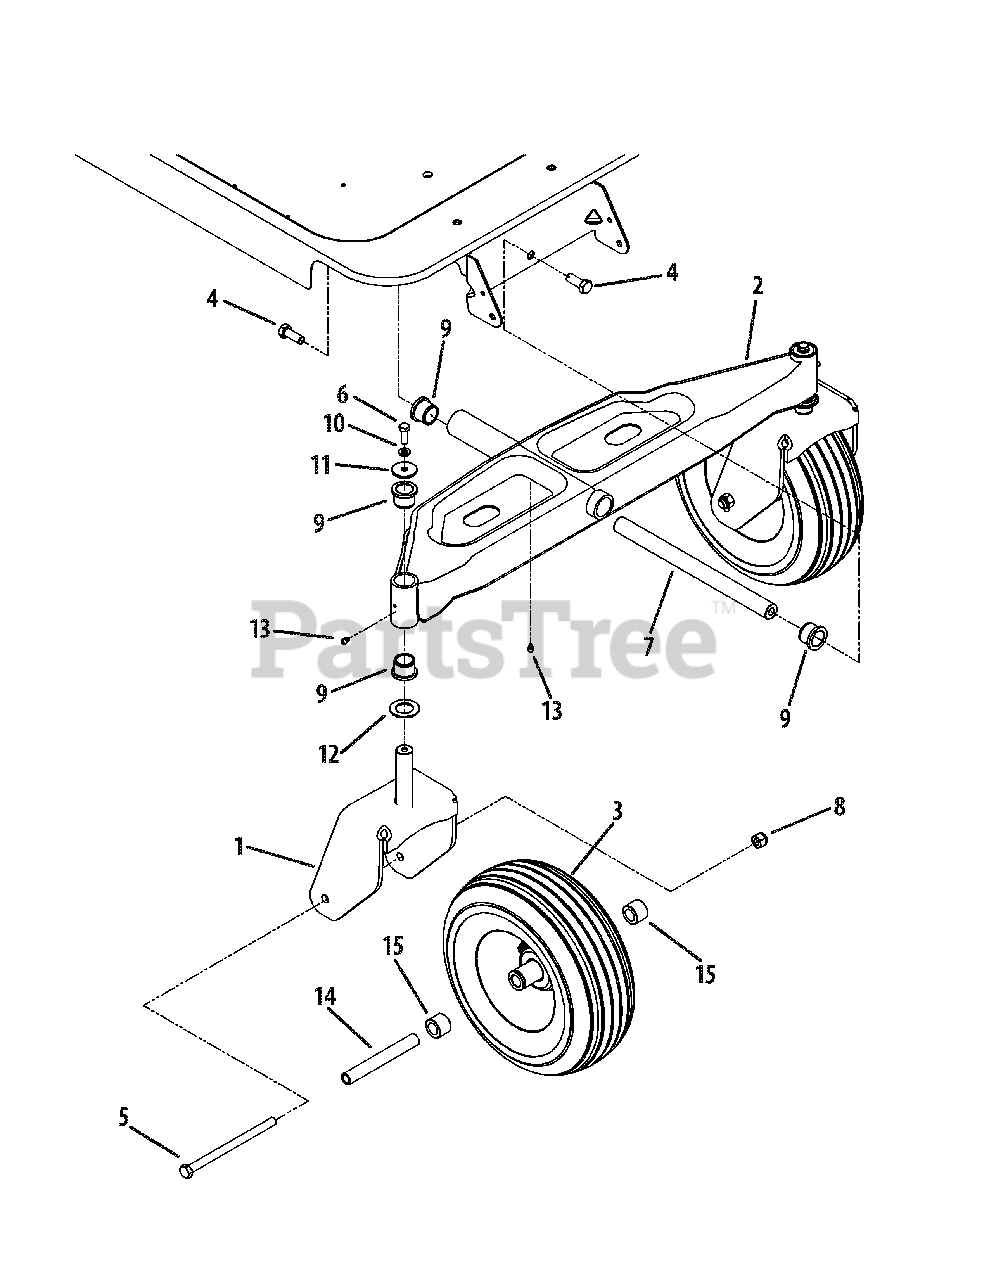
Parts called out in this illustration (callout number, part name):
1	Castor Wheel Bracket
2	Front Pivot Axle
3	Wheel Assembly, 13 x 5-6
4	Hex Lock Screw, 1.2-13 x 1.25
5	Hex Cap Screw, 1.2-20 x 7.25
6	Hex Cap Screw, 3.8-16 x 1.0
7	Axle Shaft
8	Hex Insert Lock Nut, 1.2-13
9	Flange Bearing, 1.0 x 1.246
10	Lock Washer, 3.8
11	Flat Washer, .39 x 1.5 x .134
12	Flat Washer, 1.0 x 1.75 x .10
13	Lube Fitting, 3.16 Drive
14	Spacer, .51 x .75 x 5.825
15	Hub, .76 x 1.23 x .92
